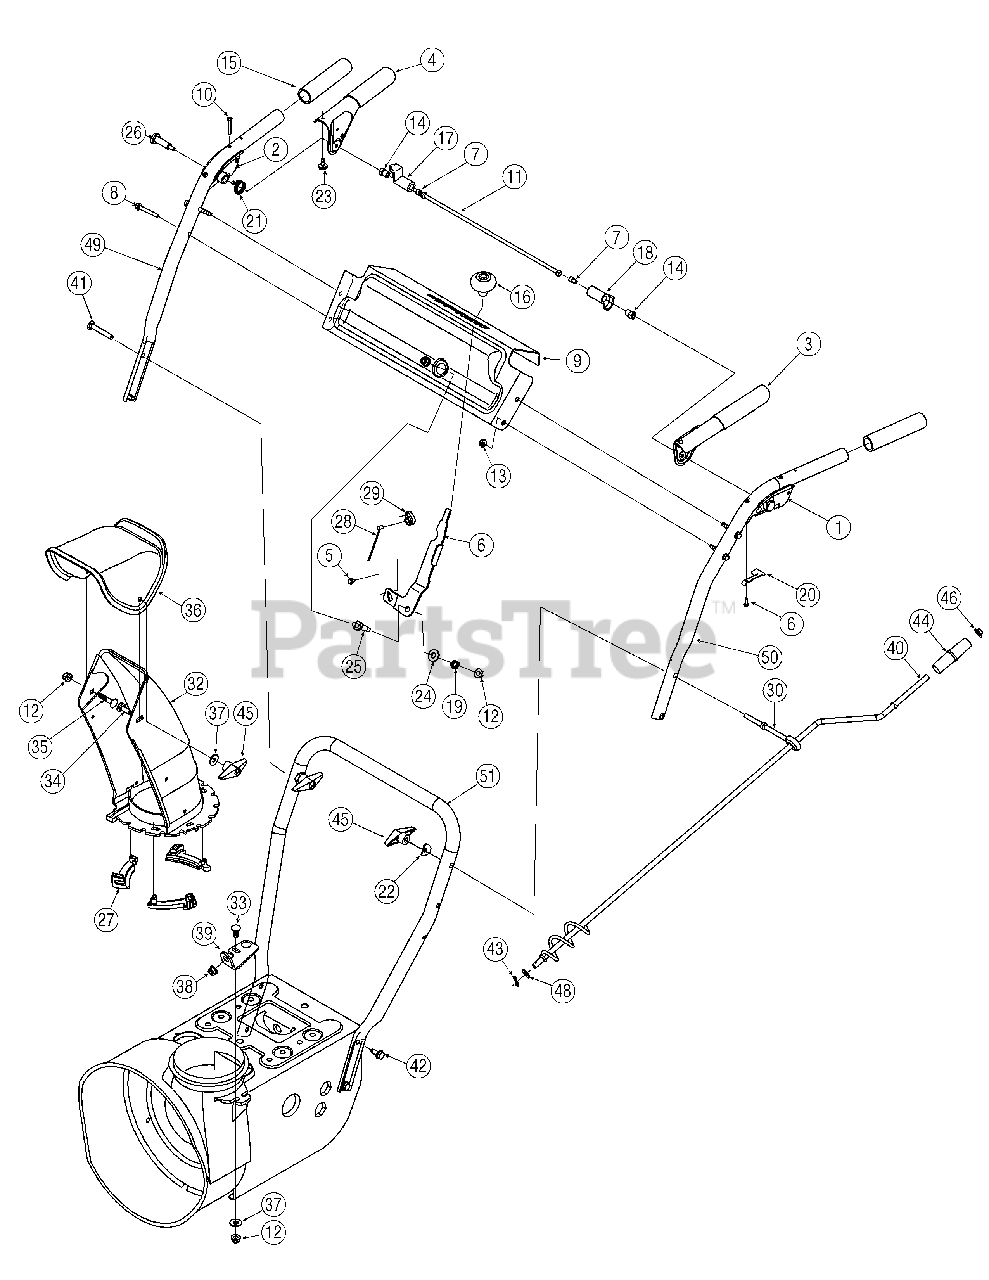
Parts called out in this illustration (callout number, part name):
1	Handle Assembly, Clutch Lock, LH
2	Handle Assembly, Clutch Lock, RH
3	Handle Assembly, Engagement LH
4	Handle Assembly, Engagement RH
5	Screw, #10-16, 0.500
6	Screw, #8-16 x .50
7	Screw, 1/4-20, .375
8	Hex Screw, 1/4-20, 1.50, Gr5
10	Screw, Machine, #10-24, 1.375
11	Pivot Rod
12	Nut, Flange Lock, 5/16-18, GrF, Nylon
13	Nut, Flange Lock, 1/4-20, GrF, Nylon
14	Nut, Hex, 1/4-20, Shoulder
15	Grip, 1.0 ID x 5.0
16	Knob, Shift
17	Lock Plate
18	Cam, Clutch Lock
19	Spring, Compression, .39x.60 x .88
20	Spring, Clutch Lock
21	Spring, Torsion, 0.8156 ID x .3038
22	Washer, Saddle, 320 x .93 x . 060
23	Bumper, Rubber, .62 OD x .22
24	Washer, Flat, .385 x .870 x .092
25	Bolt, Shoulder, 5/16-18 x 0.905, Special
26	Screw, Shoulder, .437 x 1.345, 1/4-20
27	Chute, Flange Keeper
28	Cable, Speed Selector
29	Houlder, Cable Barrel, LH
30	Eye Bolt, Chute Crank
33	Bolt, Carriage, 5/16-18, 1.0
34	Bolt, Carriage, 5/16-18, 1.0, Custom
35	Bolt, Carriage, 5/16-18, .750
36	Chute, Upper, w/ Label
37	Washer.349 ID x .879 OD x .063
38	Bushing, Plastic, .380
41	Screw, Carriage, 5/16-18, 2.25, Gr5
42	Screw, 5/16-18, 0.75, Gr5
43	Pin, Cotter, .072 x 1.13
44	Crank Knob, 1.0 Diameter x 3.2,
45	Knob Assembly, Wing Nut, 5/16-18
46	Cap, Push, 3/8 Rod
47	Grommet, .44 ID x .94 OD x.50
48	Washer, Flat, .375 x .738 x .063
